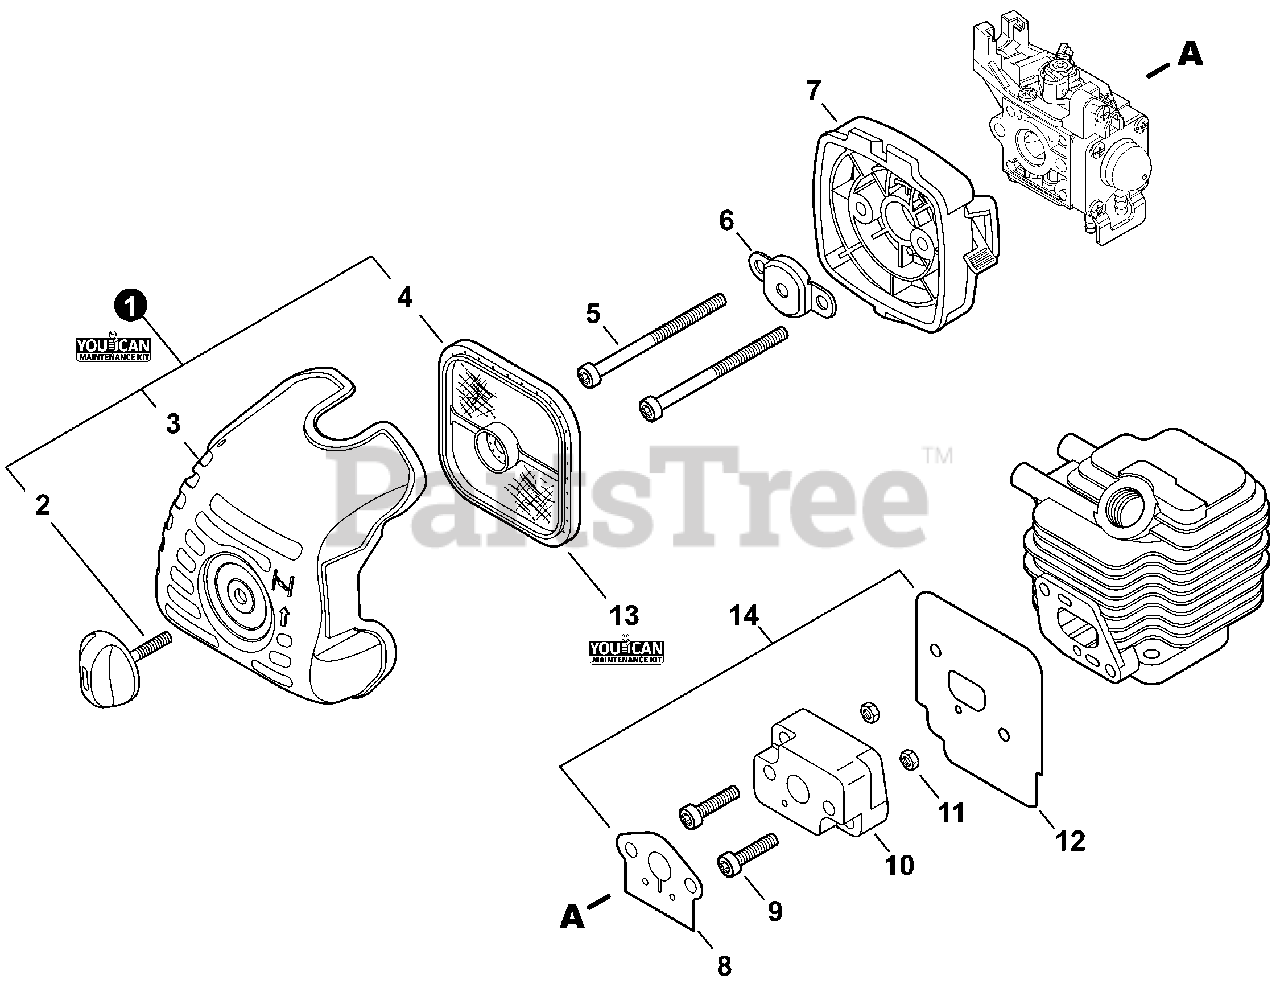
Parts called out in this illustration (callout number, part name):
1	FILTER KIT, AIR - YOUCANT
2	THUMBSCREW
3	COVER, AIR FILTER
4	FILTER, AIR - DOUBLE LAYER
5	BOLT, TORX 5x65
6	PLATE, PREVENT
7	CASE ASSY, AIR FILTER
8	GASKET, INTAKE
9	BOLT, TORX 5x20
10	INSULATOR, INTAKE
11	NUT M5
12	HEAT SHIELD, INTAKE
13	TUNE-UP KIT - YOUCANT
14	GASKET KIT: ENGINE, INTAKE, EXHAUST
